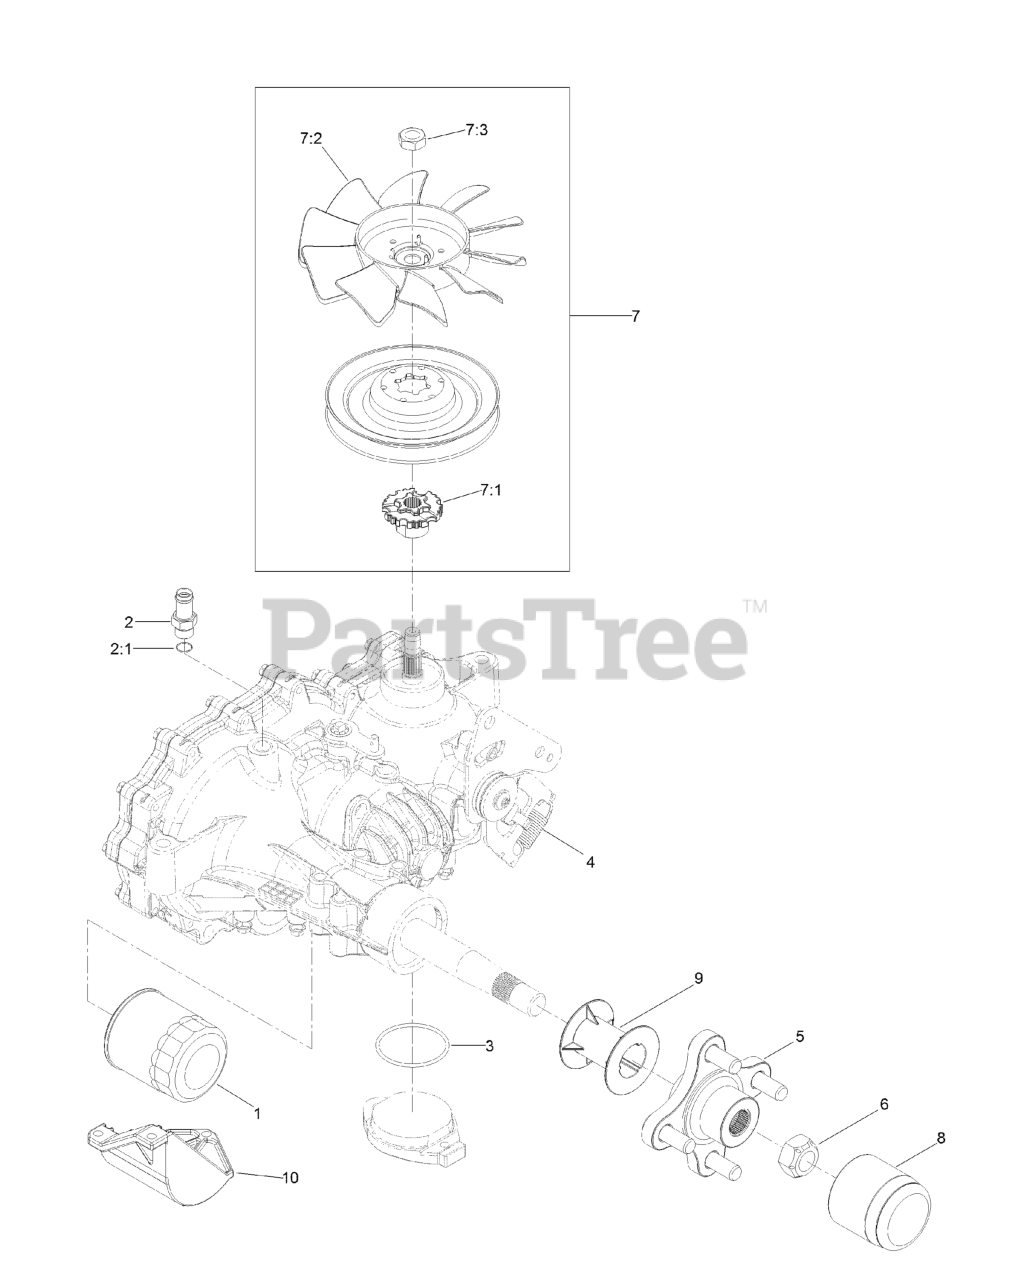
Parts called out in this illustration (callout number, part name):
1	ELEMENT-OIL FILTER, HYD
2	ADAPTER-STRAIGHT
2:1	O-RING
3	O RING-SEAL
4	SPRING-EXTENSION
5	HUB-OFFSET
6	NUT-HUB
7	FAN AND PULLEY KIT
7:1	HUB-FAN
8	CAP-AXLE, LONG
9	TUBE-AXLE
10	GUARD-FILTER, RH
